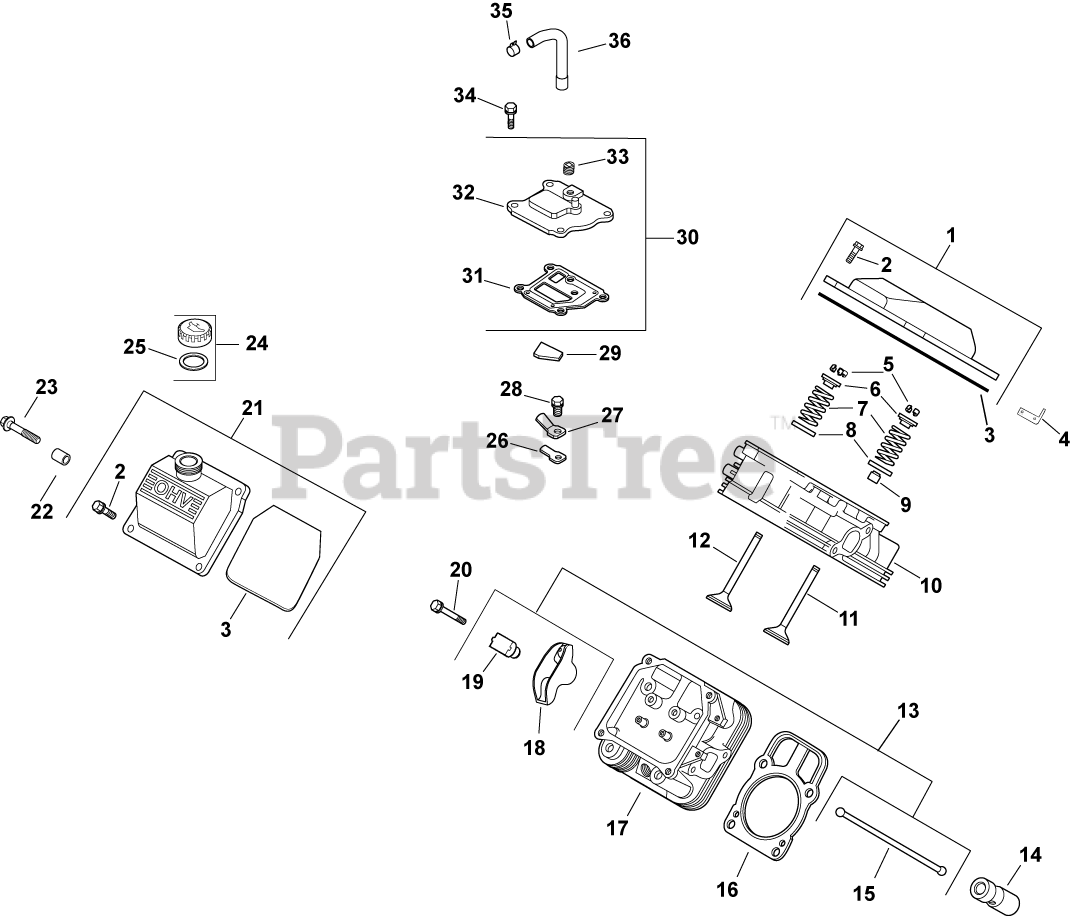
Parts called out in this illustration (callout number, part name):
1	KIT, VALVE COVER-PLAIN
2	SCREW, FLG M6X1.0X30
3	O-RING (BLACK)
4	STRAP, LIFTING-USE 25 445 03-S
5	KIT, RETAINER
6	RETAINER, VALVE SPRING - USE 25 173 28-S
7	SPRING, VALVE
8	RETAINER, SPRING
9	SEAL, VALVE STEM - (#2503214S)
10	HEAD, ASSEM CYLINDER #1 -USE 24 318 107-
11	VALVE, INTAKE (STD)
12	VALVE, EXHAUST (STD) - USE 32 016 01-S
13	KIT, VALVE TRAIN
14	LIFTER, HYDRAULIC VALVE-USE 25 351 10-S
15	ROD, PUSH
16	KIT, CYL HEAD GASKET (C17-22)
17	HEAD, ASSEM CYLINDER #2 -USE 24 318 115-
18	ARM, ROCKER
19	PIVOT, ROCKER ARM
20	SCREW, FLG M6X1.0X34
21	KIT, VALVE COVER-OIL FILL
23	SCREW - USE 62 086 08-S
24	KIT, OIL FILL CAP (YELLOW)
25	O-RING, DIPSTICK
26	REED, BREATHER
27	RETAINER, REED
28	SCREW, FLG THD FRM M5X.8X10
29	FILTER, BREATHER-USE 24 050 11-S
30	KIT, BREATHER ASSEMBLY
31	GASKET, BREATHER-USE 24 041 67-S
32	COVER, BREATHER -USE 24 033 01-S
33	PLUG, CTSK PIPE 1/8"
34	SCREW,FLG THD FRM M6X1.0X20-(#25086396S)
35	CLAMP, BAND SPRING HOSE-(#2523737S)
36	HOSE, BREATHER -USE 24 326 91-S
2401602-S	VALVE, EXHAUST (.25)
2401702-S	VALVE, INTAKE (.25)
